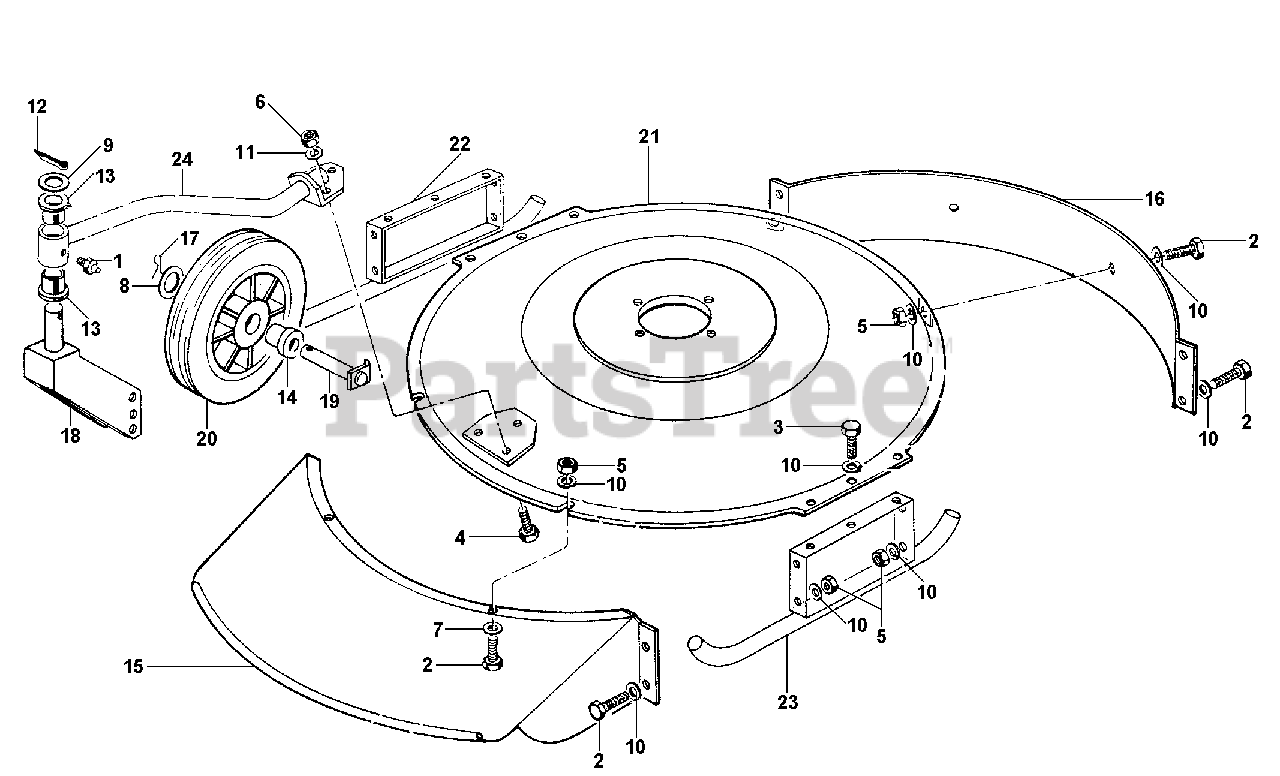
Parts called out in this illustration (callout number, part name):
1	LUBRICATOR M10
2	SCREW M8X20
3	SCREW TE M8X25
4	SCREW TE M10X30
5	NUT, SELF LOCKING M8
6	NUT, SELF LOCKING M10
7	WASHER, FLAT
8	WASHER, FLAT
9	WASHER, FLAT
10	WASHER, LOCK
11	WASHER, LOCK 10.5
12	COTTER PIN 4X30
14	SMALL WHEEL BUSHING
19	SMALL WHEEL PIN
20	SMALL WHEEL
21	MOWER PLATE
22	RIGHT SIDE SKID
23	LEFT SIDE SKID
24	CASTER SUPPORT
